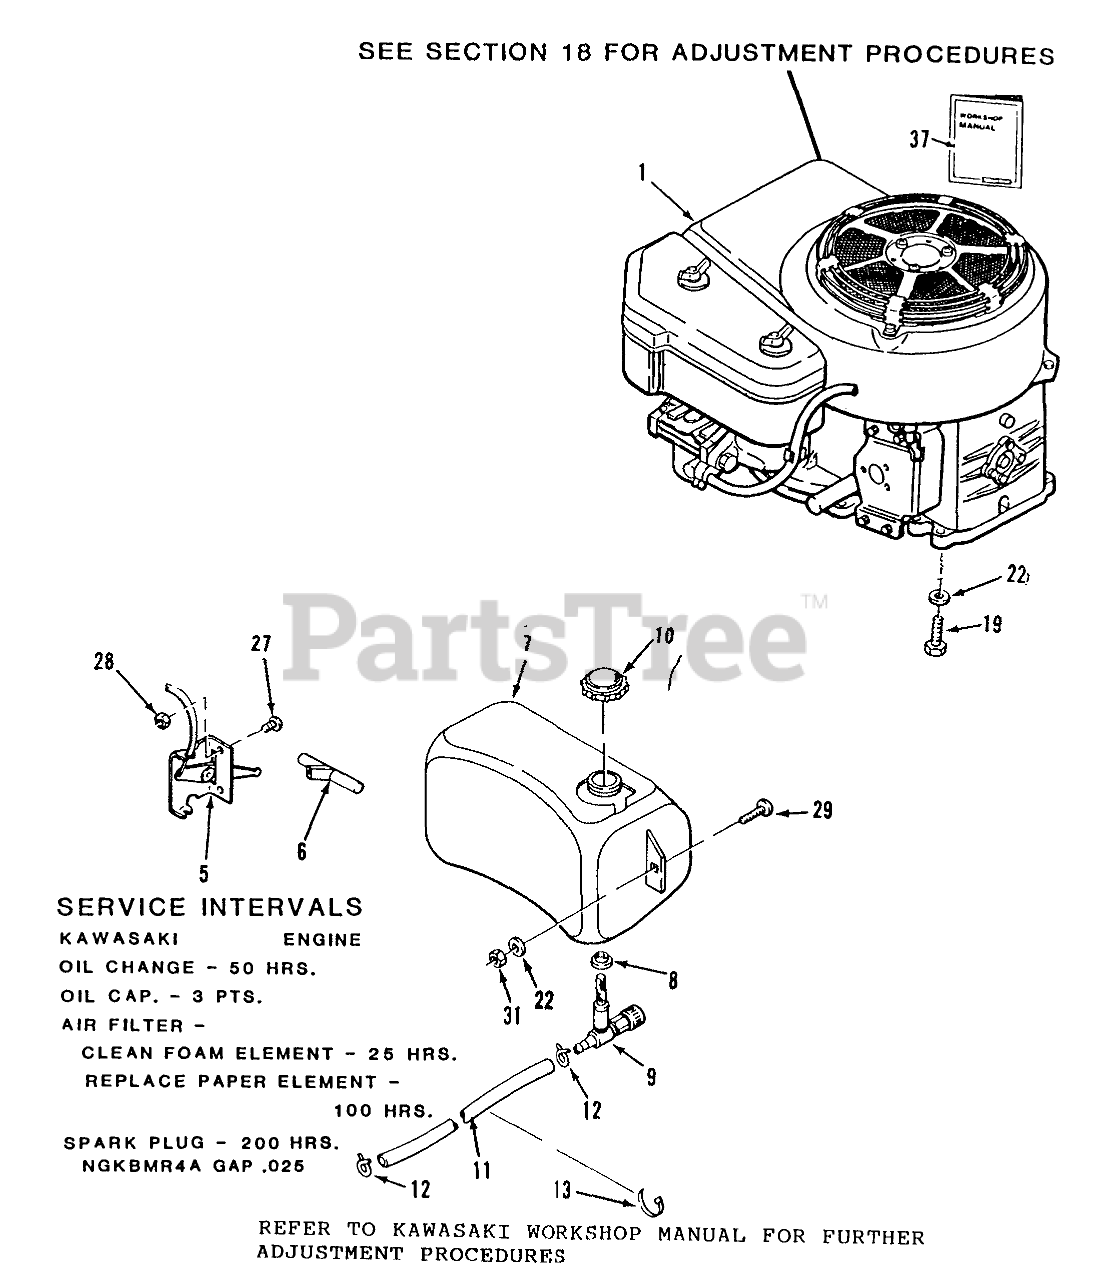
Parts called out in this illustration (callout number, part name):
1	Engine-9HP-Kawasaki Model FC 290, 210-4 Only
5	Choke/Throttle Control
6	KNOB-CONTROL
7	Fuel Tank
8	BUSHING
9	Valve
10	CAP GAS
11	Fuel Line
12	Clamp
13	Cable Tie
19	HHCS
22	WASHER 5/16 SAE
27	Screw
28	Nut
29	Bolt
31	Nut
37	Kawasaki FB460V Workshop Manual
